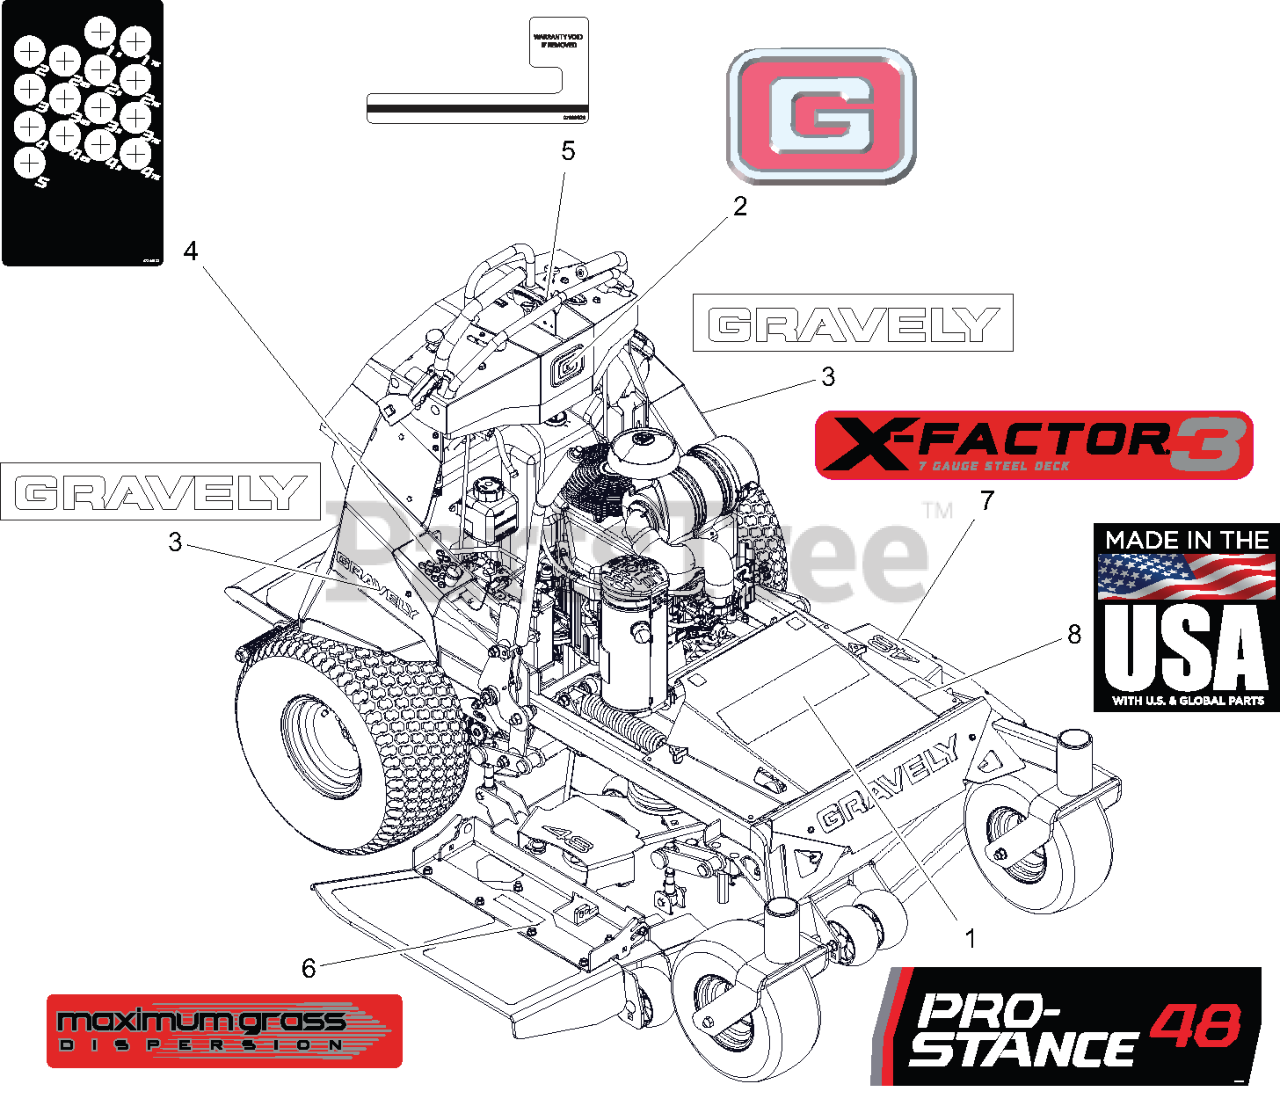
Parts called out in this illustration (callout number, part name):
1	DECAL, PROSTANCE 48
2	DECAL, GRAVELY BRAND
3	DECAL, 9.5" GRAVELY LOGO
4	DECAL, DECK - HEIGHT ADJUST
5	DECAL,HOURMETER - SECURITY
6	DECAL, DECK - MAX GRASS
7	DECAL, DECK - X-FACTOR 3
8	DECAL, MADE IN USA
